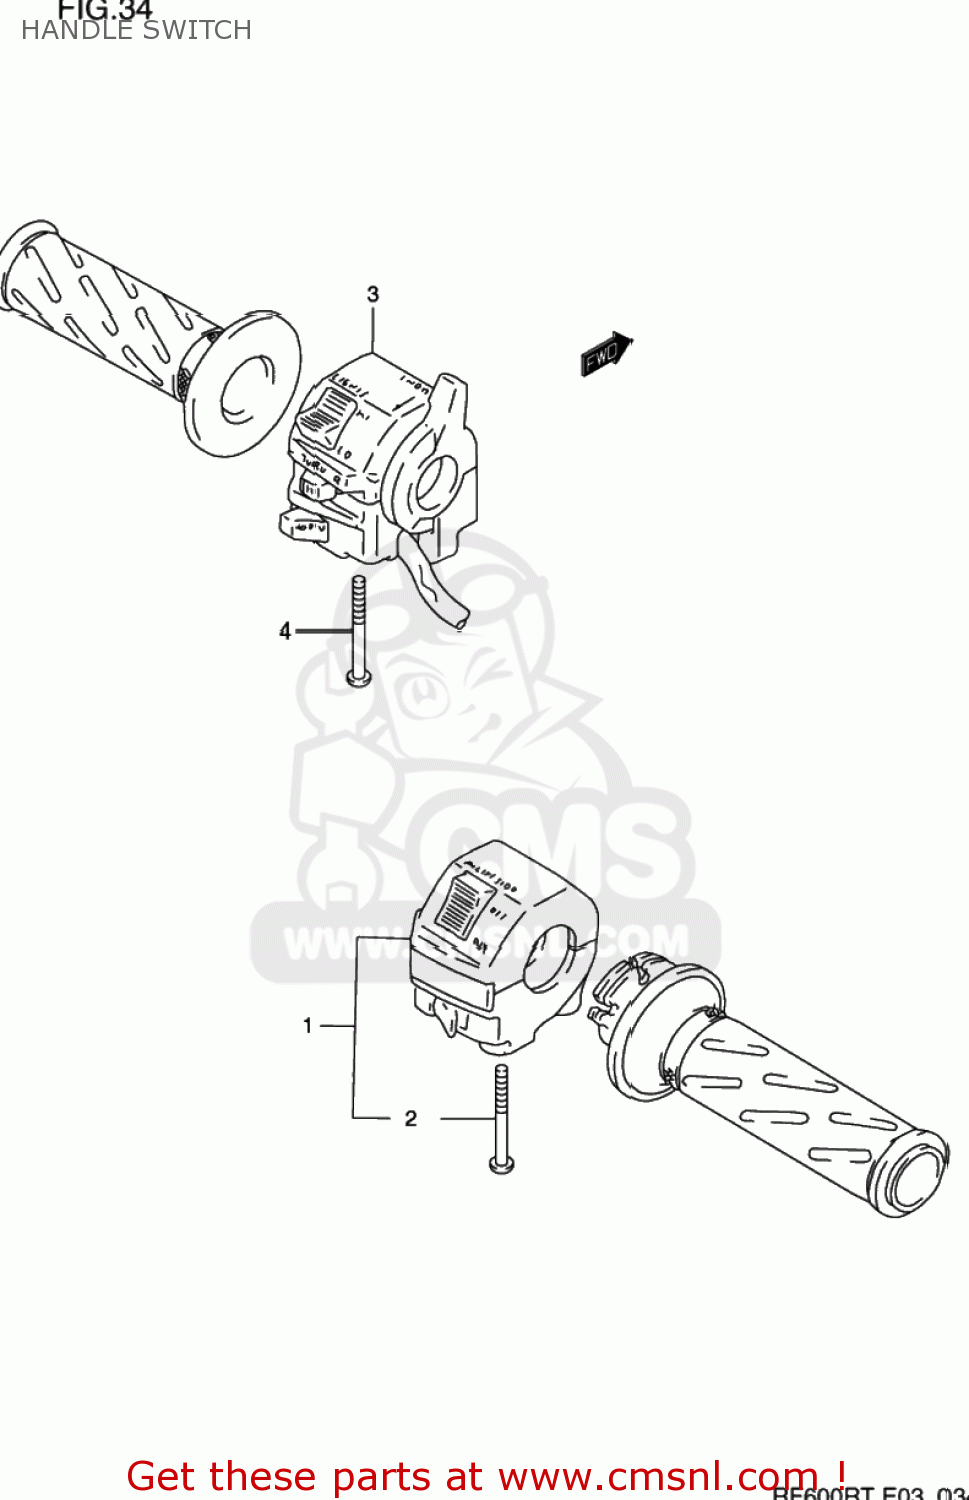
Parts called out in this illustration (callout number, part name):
1	SWITCH ASSEMBLY,HANDLE,RIGHT
2	SCREW, 5X45
3	SWITCH ASSY,HANDLE,L
4	SCREW
